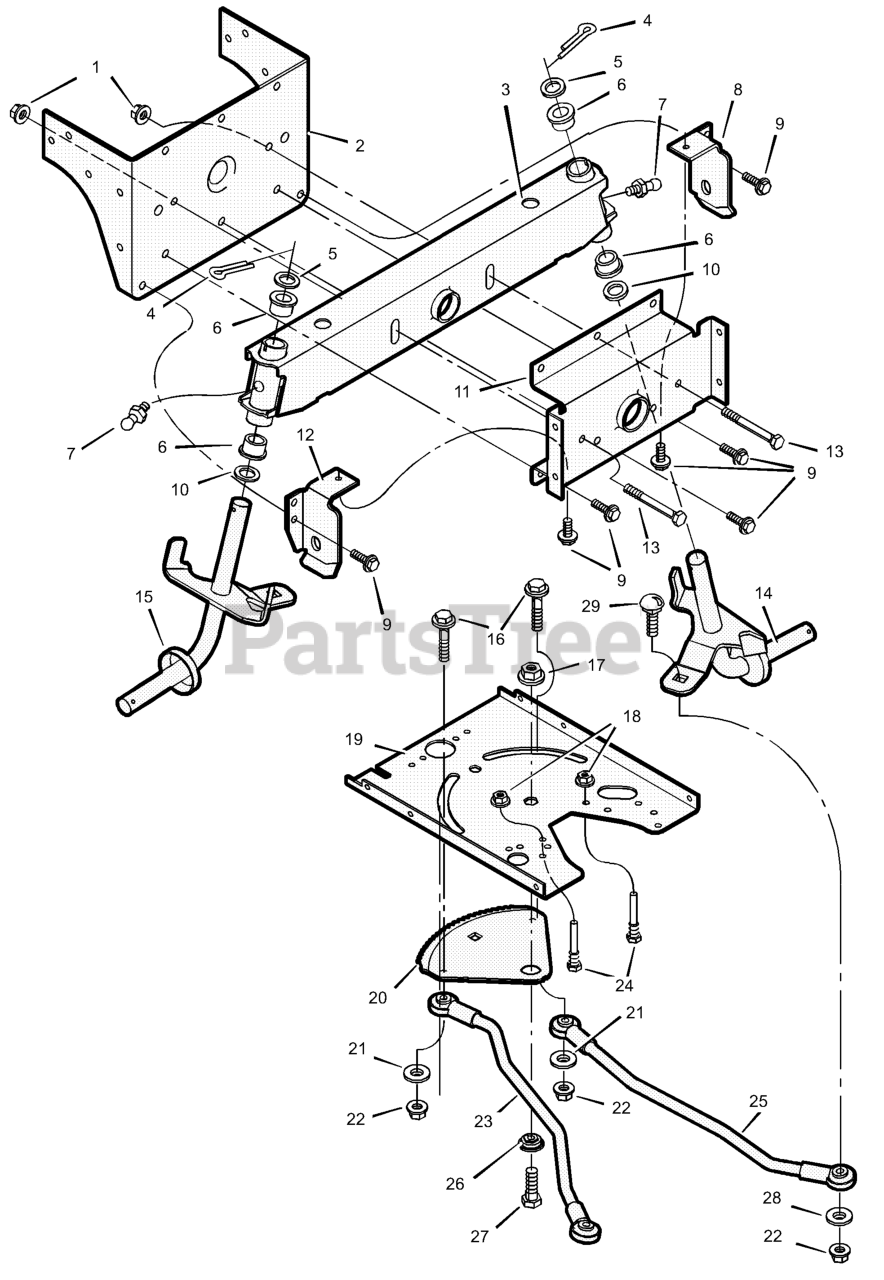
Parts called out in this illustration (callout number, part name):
1	Locknut, Flange
2	Bracket, Rear Hanger
3	Assembly, Axle (with Zerk)
4	Pin, Cotter
6	Bearing, Spindle
7	Fitting, Grease
8	Hanger, Left Deck
11	Hanger, Axle
12	Hanger, Right Deck
13	Bolt, Hex
14	Assembly, Left Spindle
15	Assembly, Right Spindle
16	Bolt, Shoulder
17	Locknut, Flange
18	Locknut, Flange
19	Plate, Steering Mount
20	Gear, Sector
22	Nut, Flange Centerlock
23	Link, Drag -Right
24	Guide, Belt
25	Link, Drag -Left
26	Bearing, Sector Gear
27	CAPSCREW, Hex Head, 5/16-18 x 1
28	Washer
29	Bolt, Carriage
